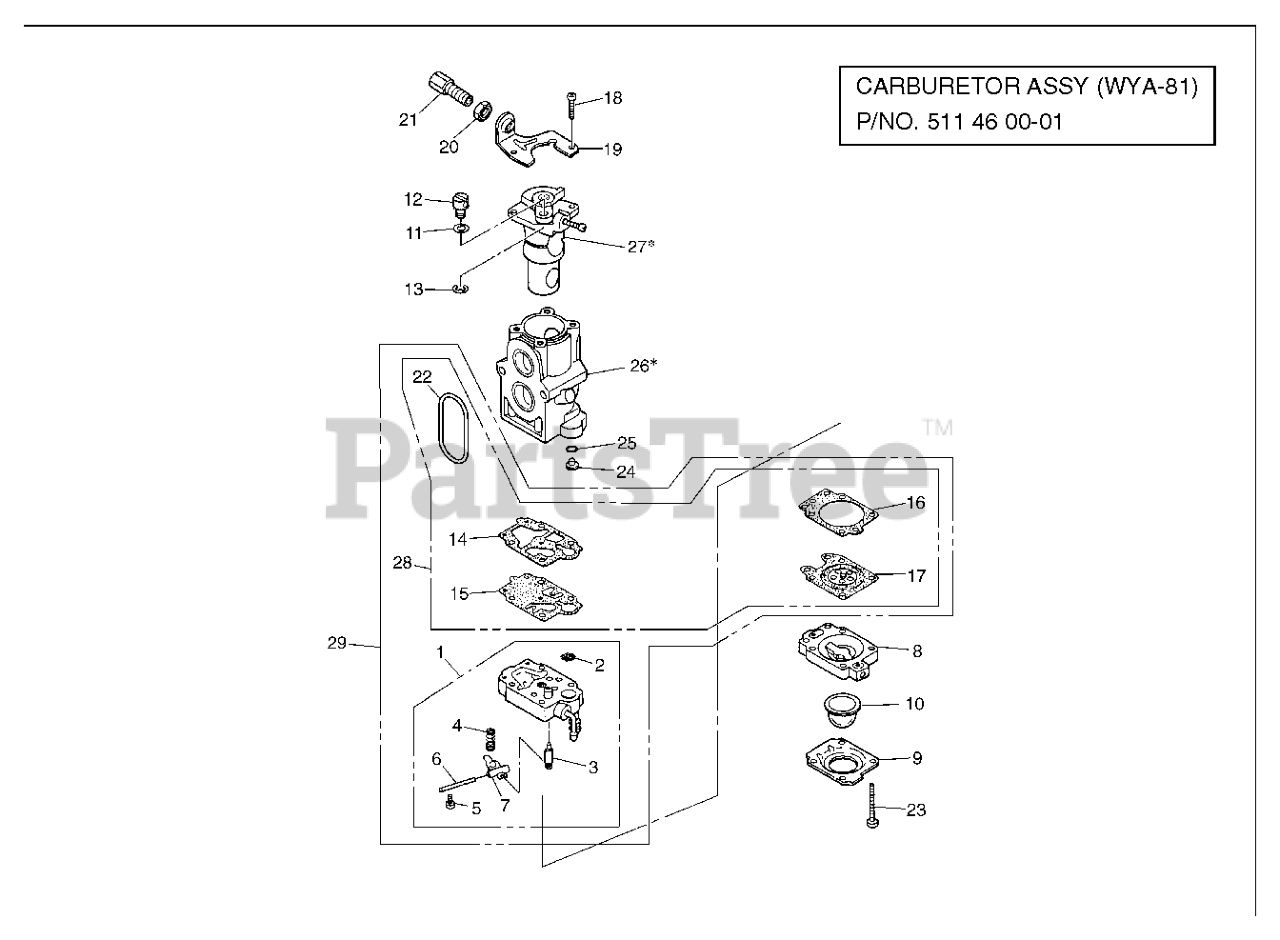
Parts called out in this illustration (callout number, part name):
1	BODY-A-PUMP
9	1OVER
11	WASHER
12	SWIVEL
13	RING
15	DIAPHRAGM
17	DIAPHRAGM
18	SCREW
19	BRACKET
20	NUT
21	ADJUSTER
22	RING
26	CARBURETOR ASSY
27	CARBURETOR ASSY
28	GASKET KIT
29	REBUILD KIT
